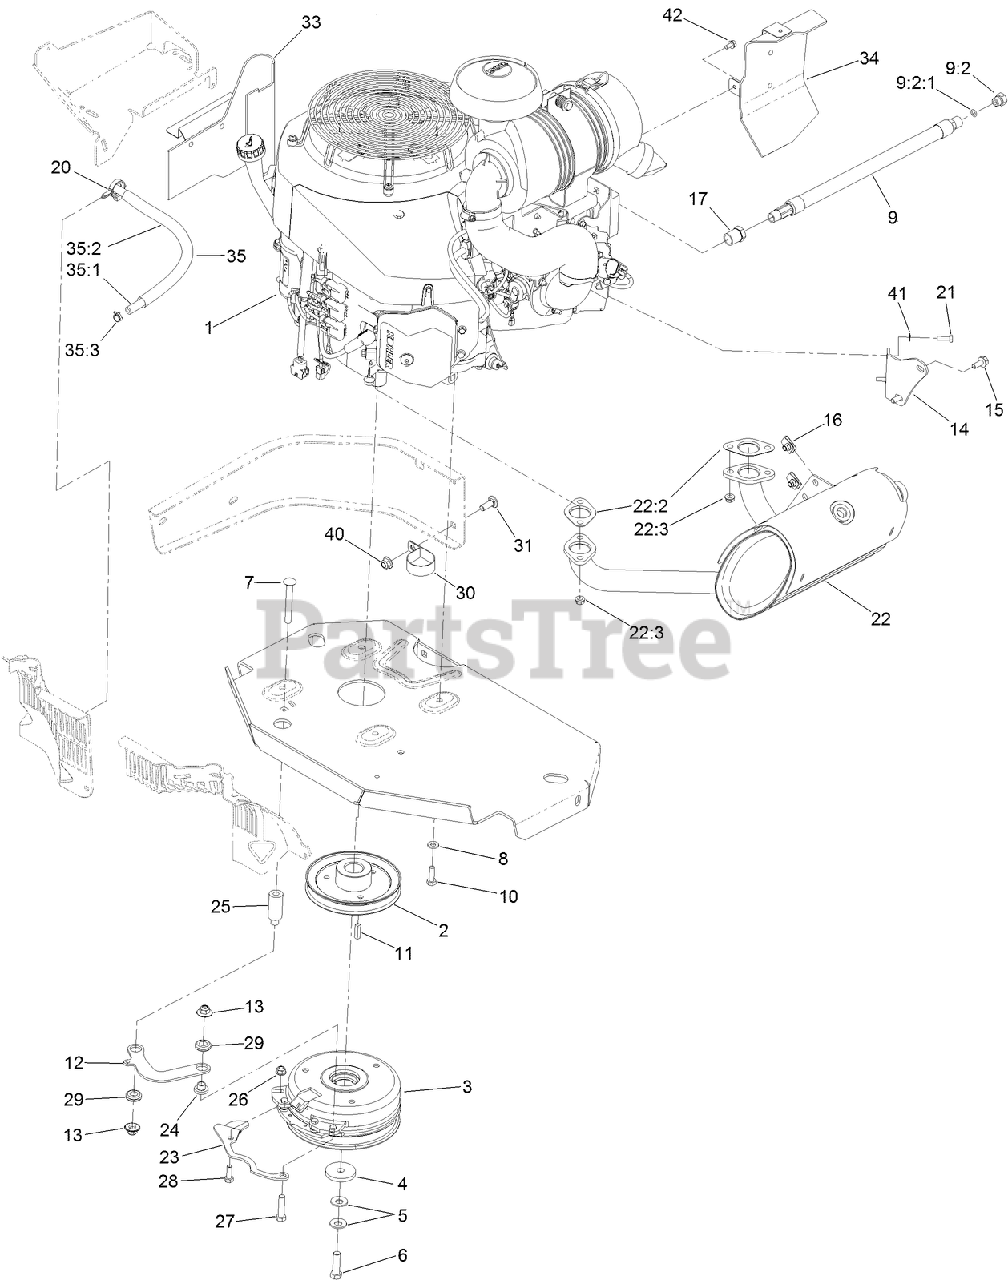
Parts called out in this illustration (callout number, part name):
1	ENGINE-KOHLER, ECV940 EFI-EGOV
2	SHEAVE
3	CLUTCH KIT
4	WASHER-CLUTCH
5	WASHER-SPRING
6	SCREW-HH
7	SCREW-CARR
8	WASHER-SPRING
9	OIL DRAIN HOSE ASM
9:2	PLUG-HH
9:2:1	O-RING
10	SCREW-HH
12	LINK-ANCHOR, CLUTCH
13	NUT-FLANGE, NI
14	Bracket-Muffler
15	SCREW-HHF
16	NUT-U
17	BUSHING
20	CLAMP-HOSE
21	SCREW-HH
22	MUFFLER KIT
22:2	GASKET-EXHAUST
22:3	NUT-FLANGE, LOCK
23	BELT-GUIDE
24	SPACER
25	SPACER
26	NUT-HF, NI
27	SCREW-HH
28	SCREW-HH
29	GROMMET-RUBBER
30	CLAMP-R
31	SCREW-CARR
33	BAFFLE-RH
34	BAFFLE ASM
35	FUEL LINE ASM
35:1	HOSE-FUEL
35:2	SLEEVE-THERMAL
35:3	CLAMP-HOSE
40	NUT-HF, NI
41	WASHER-SPRING
42	SCREW-HWH
